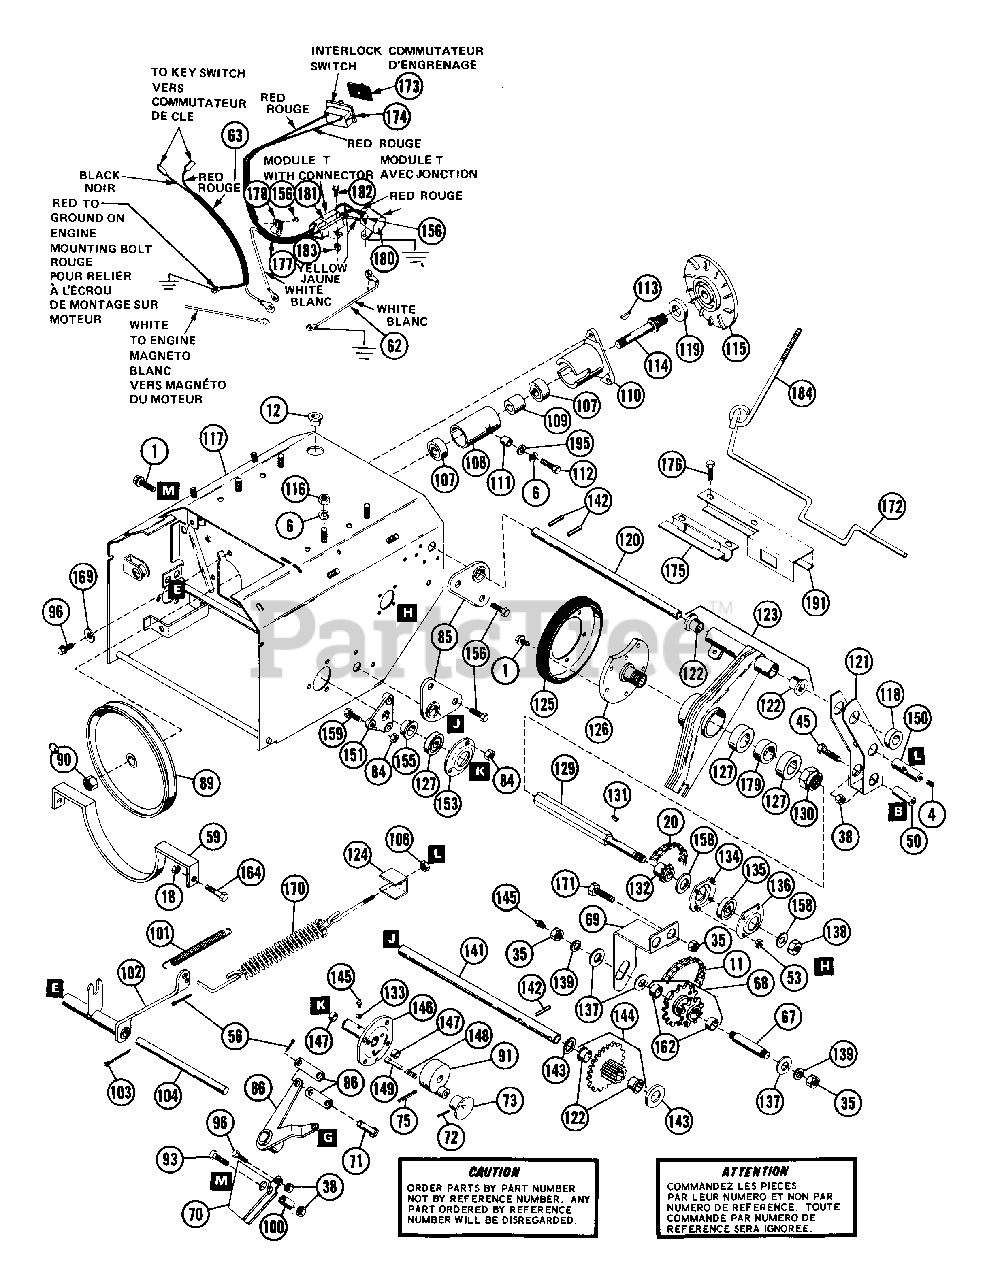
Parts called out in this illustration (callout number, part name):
1	BLT-SERHFWH .31-18X.50 PL
4	SCR-SET .32-18X.38 SKHCUPNL OH
6	WSHR-LK .312X.097 PL HVY
11	PINION CHAIN
12	SNAP BUSHING-.437
18	NUT-LK-CTR .250-20 PL
20	IDLER CHAIN
35	NUT-HEX .375-16
38	NUT-LK .312-18 GR A PL
45	BLT-HEX .31-18X.75 PL GR2
50	ROD ADAPTER
53	NUT-LK DUAL FACE 10-24 PL
56	PIN-COTR .09X.75 PL
59	BELT RETAINER
61	BUTTON PLUG 1.0
62	WIRE - GROUND
63	SHORTING WIRE
66	LEVER - SHIFT ARM
67	REDUCTION SHAFT SERVICE ASSEMB
68	SPROCKET ASSEMBLY
69	SUPPORT
70	BRACKET SHIFT LEVER
71	CLEVIS PIN
72	PIN-ROLL .093X1.00
73	KNOB
75	PIN-GRV .250X1.75 TP C
84	NUT-LK-FLG .250-20 PL
85	SUPPORT, SHAFT
86	SHIFT LINK
89	PLY-V 8.00 X 1.0 W/KEY CLARK
89	PLY-V 6.00 X .63 W/KEY CLARK
90	NUT-LK-NYL.625-18 PL
91	LOCKOUT HUB
93	BLT-HEX .31-18X3.00 PL GR2
96	BLT-HEX .31-18X.50 PL GR2
100	SPACER .5 X .33 X 2.4
101	SG-TENS .080X.73X3.06 WLD 20
102	FORK, CLUTCH
103	PIN-COTR .09X1.0 PL
104	ROD, FORK PIVOT
106	NUT-LK-NYL.312-18 PL
107	BRG-BALL .625X1.375X.44
108	SPINDLE HOUSING
109	BEARING SPACER
110	DRIVE SPINDLE HOUSING
112	BLT-HEX .31-18X1.00 PL GR 2
113	KEY-WDRF .125X.500X.203 SAE 3
114	SPINDLE
115	DRIVE PLATE
116	NUT-HEX .312-18
117	FRAME - TRACTOR 6 HP
117	FRAME - TRACTOR
118	SPACER 1.00 X .64 X .38
119	DRIVE DISC SPACER 1.3X.76X.19
120	CARRIER SHAFT
121	CLUTCH ENGAGEMENT YOKE
122	BSHG-FLG .625X.750X.500X.875BR
123	DISC CARRIER SERVICE ASSEMBLY
124	ADAPTER SPACER
125	FRICTION DISC
126	FRICTION DISC HUB
127	BRG-BALL .876 X 1.750 X .50
129	HEX SHAFT
130	NUT-LK-NYL .875-14
131	KEY-WDRF .125X.625X.250 SAE5
132	9 TOOTH SPROCKET
133	WSHR-LK .250X.047 LT PL
134	BEARING FLANGE
135	BRG-BALL .500X1.38X.437
136	BEARING FLANGE
137	WSHR-FL-STL .382X.812X.062
138	NUT-LK-CTR .50-20 PL
139	WSHR-LK .375X.130
141	PINION SHAFT
142	PIN-ROLL .156X1.00
143	WSHR-FL-STL .630X1.005X.062 PL
144	PINION AND SPROCKET ASSY.
145	SPIN DRIVE ZERK FITTING
146	L. H. AXLE ASSEM
146	L H AXLE ASSEMBLY
147	BSHG-SLV .562X.625X.625 BRZ
148	PIN
149	SG-COMP .028X.34X1.062 WLD75
150	ADAPTER
151	SUPPORT, BEARING
153	BEARING FLANGE
155	BSHG-FLG.875X1X.625X1.250 BR
155	BSHG-FLG .750X1.000X.625X1.250
156	BLT-SERHFWH .25-20X.50 PL
158	WSHR-FL-STL .505X1.000X.062
159	SCR-SLTR-SERNK .25-20X.62 PL
162	BSHG-SLV .500X.625X.500 BR
164	BLT-HEX .25-20X.50 PL GR2
169	WSHR-LK-INT .313X.030 PL
170	SPRING ASSEMBLY
171	SCR-TAP .250-20X.50 HXSLHDPL
172	SWITCH ACTUATOR
173	SWITCH BOOT
175	ROD RETAINER
176	SCR-TAP 10-24X.375 HWH PL TR
177	WIRING HARNESS
180	MODULE T SERVICE ASSEMBLY
181	CONNECTOR
182	BLT-HEX 10-24X.38 PL GR2
183	NUT-KEPS 10-24 PL
184	LOWER ROD INTERLOCK
191	SWITCH RETAINER
195	WSHR-FL-STL.344X.688X.065PL
